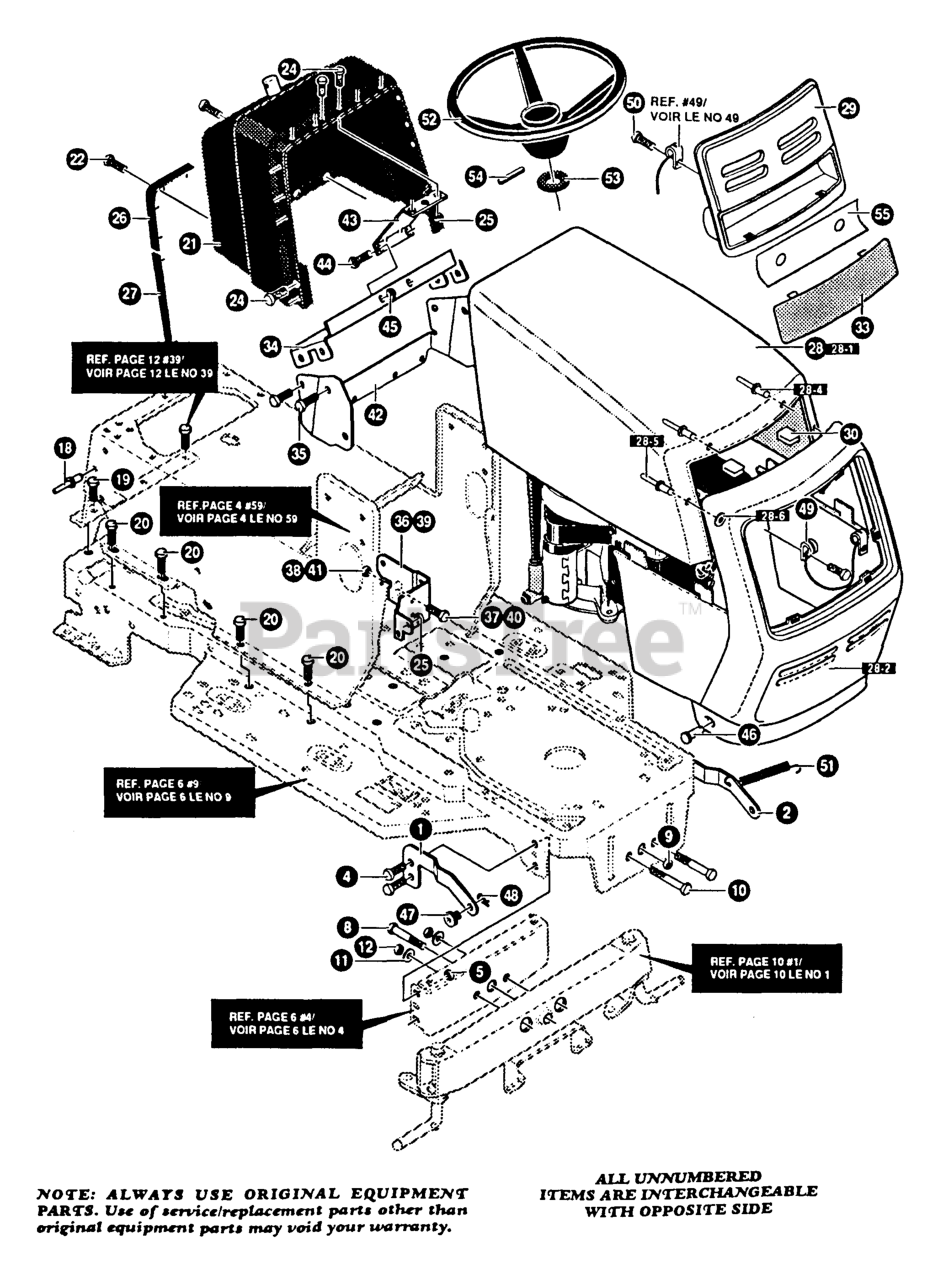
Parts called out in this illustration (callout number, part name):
1	BRKT, HOOD, RH
2	BRKT, HOOD, LH
4	SCREW
11	WASHER
12	NUT
18	RIVET
19	SCREW
26	BUMPER
27	BUMPER
28	HOOD ASSY
28-6	WASHER
29	INSERT, GRILLE
34	SUPPORT, STEERING
36	BRACKET, DASH
39	BRKT, DASH
43	DASH SUPPORT BRACKET
47	BEARING HOOD
49	LANYARD, HOOD
50	SCREW
52	STEERING WHEEL
53	SPACER
54	PIN, SPRING
55	FOIL, LENS
